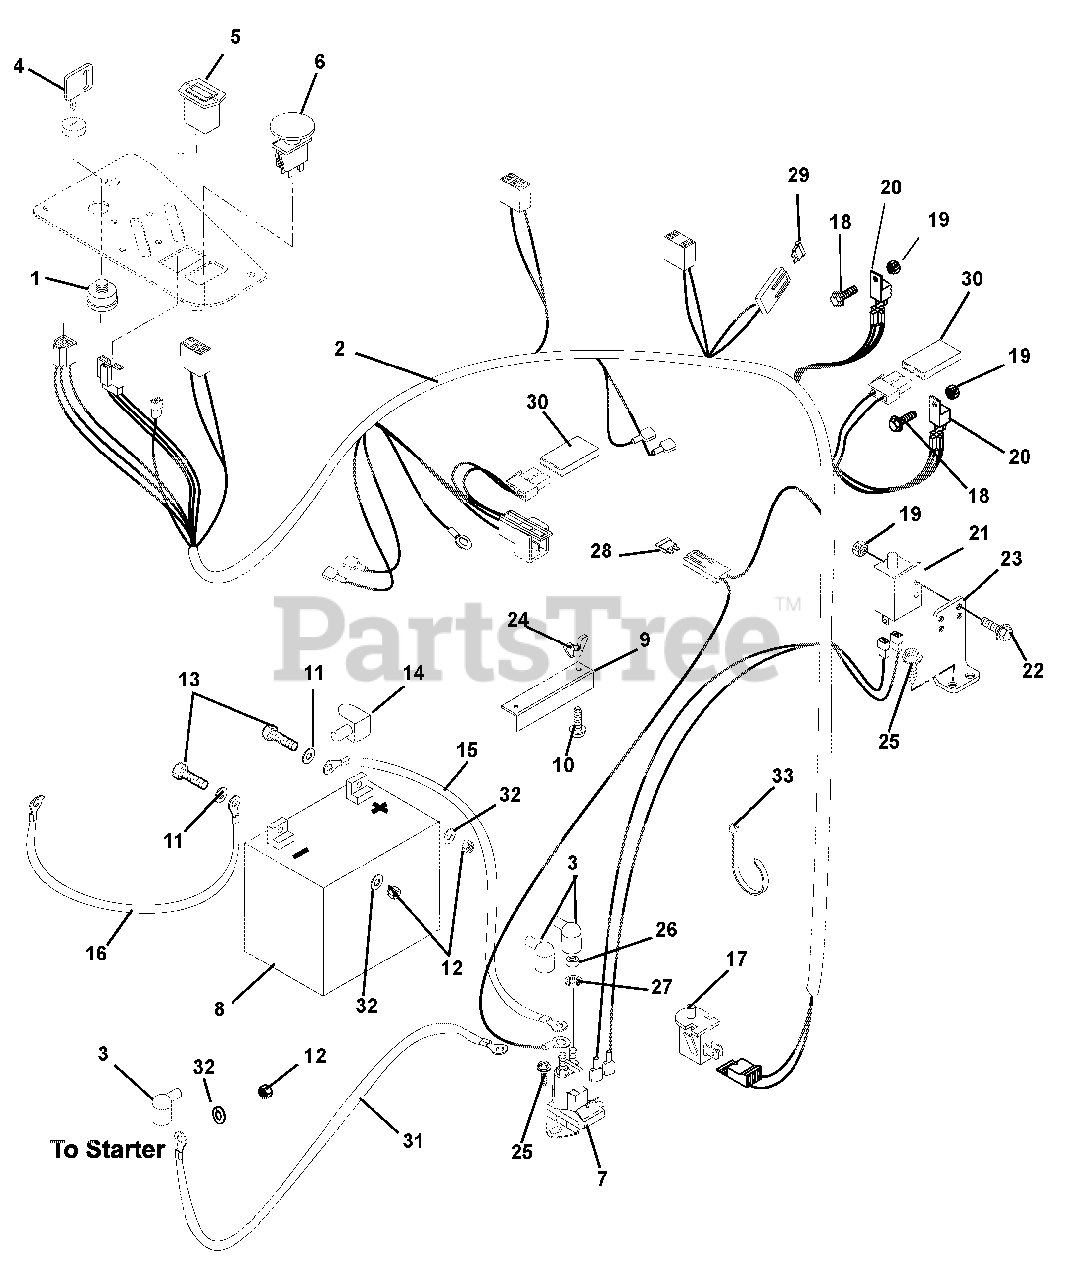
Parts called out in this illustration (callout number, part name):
1	Key Switch
2	Harness, Wiring IZ/CZ 6-Pin
3	Boot, Eyelet Terminal
4	Key with Shield
5	Hour Meter – Digital
6	Switch, Clutch With Retainer Ring
7	Solenoid
9	Hold Down
10	Bolt, Round Head Square Neck .25-20 x 7.50
11	Washer, Flat Steel .281 x .620 x .065
12	Nut, Hex .25-20
13	Bolt, Hex .25-20 x .75 Grade 5
14	Insulator
15	Cable, Positive Battery 9.00"
16	Ground Cable
17	Switch, Snap Mounting (N.O.)
18	Screw, Machine 10-24 x .50 Hex Washer Head
19	Nut, Locking Nylon 10-24 With Insert
20	Relay (Included with Harness)
21	Switch, Single Pole
22	Screw, Machine 10-24 x .75 Hex Washer Head
23	Mount, Brake Switch
24	Nut, Locking Wing .25-20
25	Screw, Tapping .25-20 x .50 Hex Washer Head
26	Nut, Jam .31-24
27	Washer, Locking .31 x .078 Regular
28	Fuse, 25 Amp (Included with Harness)
29	Fuse, 20 Amp
30	Diode, Connector Shell
31	Cable, Starter
32	Washer, Lock .25 x .062
33	Tie, Cable LG 5.50
